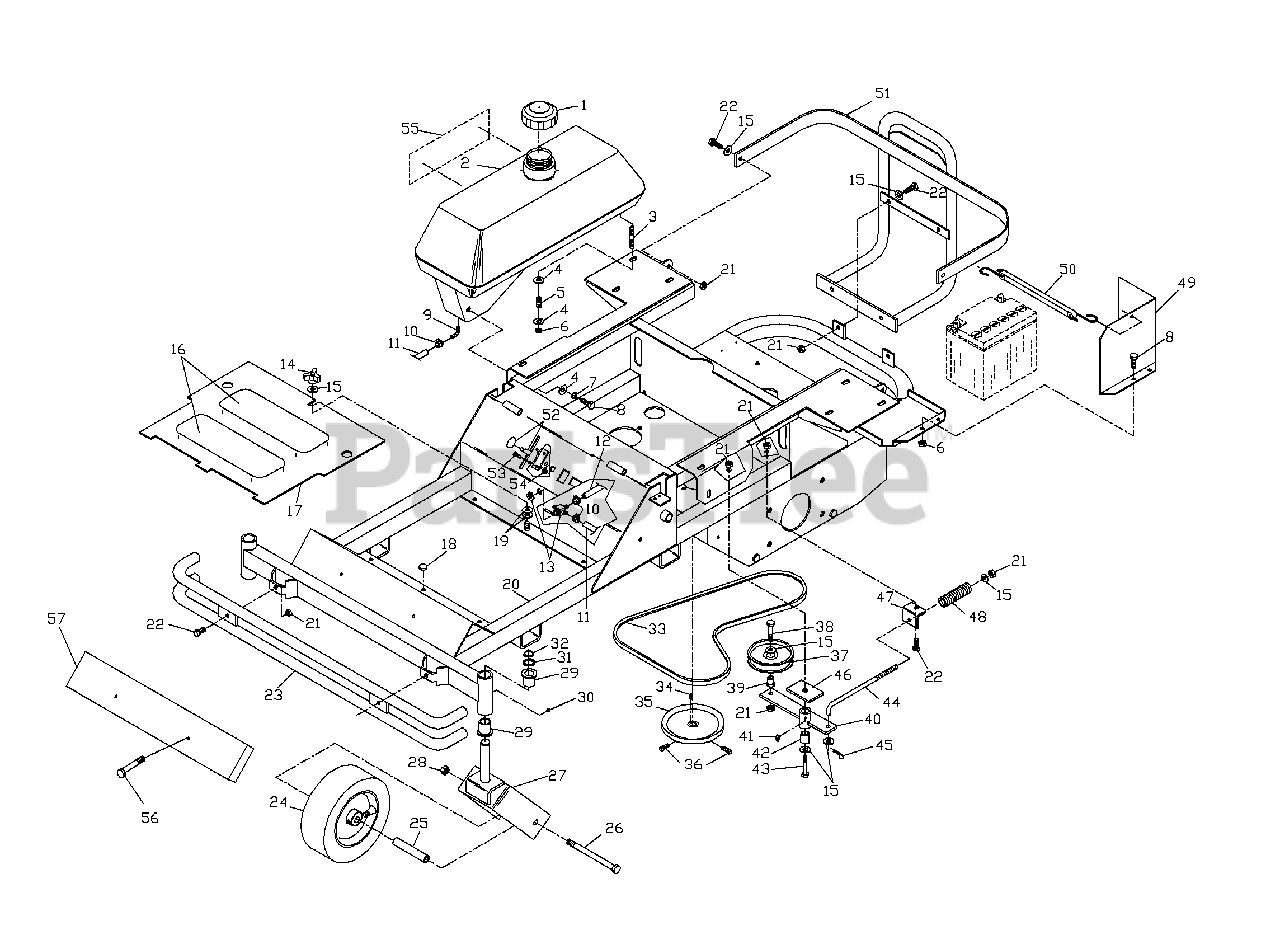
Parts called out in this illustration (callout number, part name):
1	FUEL CAP
2	FUEL TANK RT.
3	5/16C STUD
4	5/16 FLAT WASHER
6	NUT 5/16C CENTERLOCK
7	5/16 LOCKWASHER
8	HCS 5/16C X 3/4
9	90 DEG. HOSE BARB
10	HOSE CLAMP
11	FUEL LINE, TANK
12	FUEL LINE, ENGINE
13	FUEL VALVE
15	3/8 FLAT WASHER
16	ANTI-SKID PAD
17	FOOTPLATE
18	BUMPER, RUBBER
19	3/8 DISC WASHER
20	FRAME W/DECALS (KAW)
20	FRAME W/DECALS (KOHLER)
21	NUT 3/8C CENTERLOCK
22	HCS 3/8C X 1
23	BUMPER, FRONT
24	CASTER TIRE(COMPLETE)
24	CASTER TIRE(COMPLETE) AFTER 04/2002
24	TIRE - AFTER 04/2002
24	RIM - AFTER 04/2002
24	ROLLER BEARING
24	ZERK
24	FLANGED BEARING
26	HCS 1/2C X 5 1/2
27	YOKE WELDMENT
28	NUT 1/2C NYLOC
29	FLANGE BUSHING
31	MACHINERY BUSHING
32	7/8" RETAINING RING
34	KEY 5 MM SQ. X 25 MM
36	5/16C X 5/8 SQ. HEAD
37	IDLER PULLEY
38	HCS 3/8C X 1 3/4
39	IDLER FLANGE BUSHING
40	IDLER ARM WELDMENT
41	45 DEG. ZERK
42	PIVOT BUSHING
43	HCS 3/8C X 3
44	TENSION ROD
45	COTTER PIN
46	SUPPORT PLATE
47	TENSION BRACKET
48	COMPRESSION SPRING
49	BATTERY GUARD W/DECALS
50	BATTERY STRAP
51	ENGINE GUARD W/DECALS
52	THROTTLE CABLE
53	#10-24 X 1/2 HCS
54	#10-24 NYLOC NUT
55	DECAL, ZTH4218
55	DECAL, ZTH4221
55	DECAL, ZTH4818
55	DECAL, ZTH4820
55	DECAL, ZTH4821
56	HCS 3/8C X 2 1/4 GD5
57	WEIGHT BLOCK
58	CHOKE CONTROL (KOHLER)
